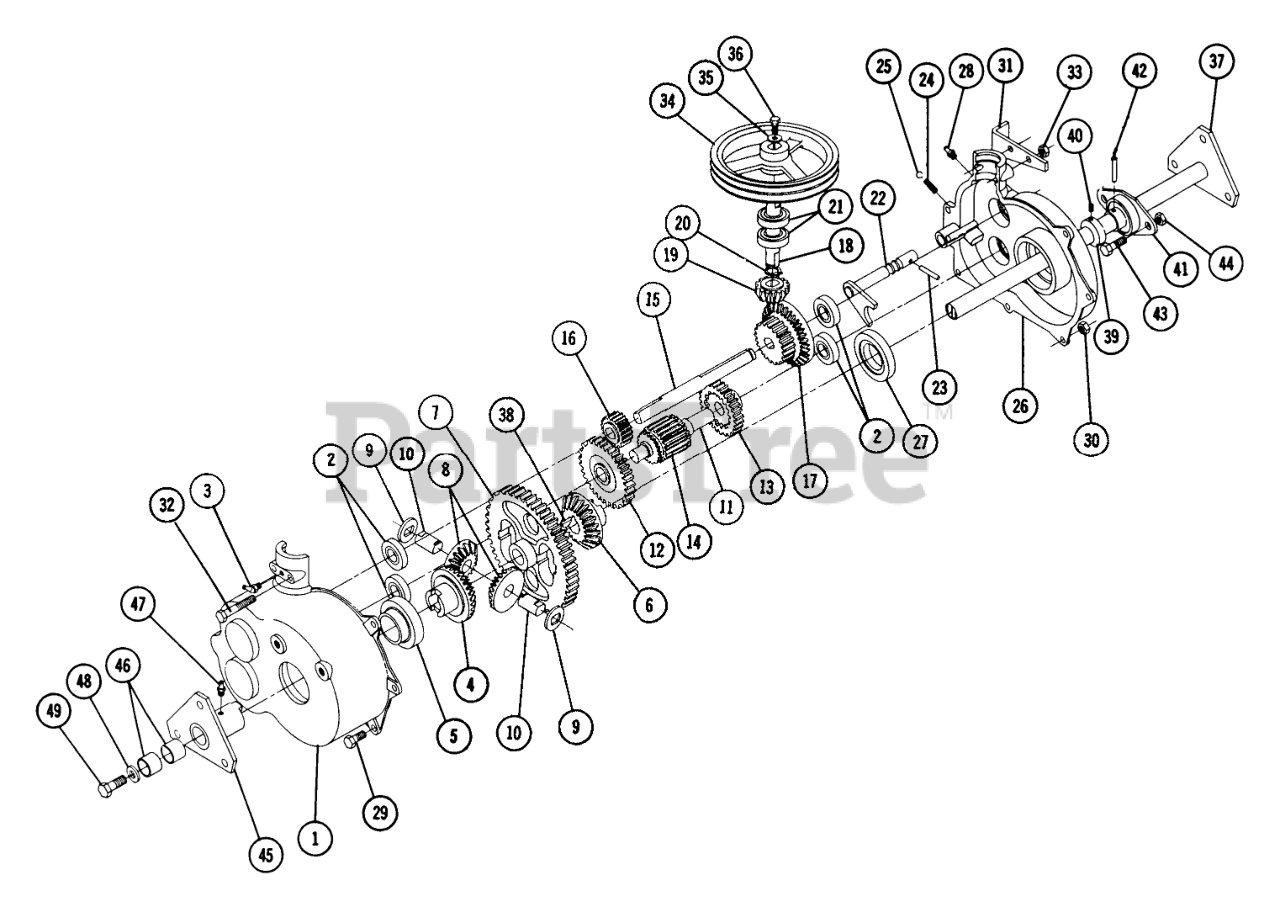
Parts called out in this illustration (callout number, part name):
3	FITTING-GREASE
20	SNAP RING- 5/8 EXT
23	PIN-SPIROL
25	BALL-DETENT
29	Bolt, 5/16-18 X 7/8
30	Nut 5/16-18 Keps
31	Bracket Shift Rod
32	Bolt Hex 5/6-18 X 2-1/2
33	Nut-Nylok
35	Washer
36	Bolt-Hex 5/16-18 x 5/8 Nylok
38	WOODRUFF KEY
40	Set Screw 1/4-20 x 1/4
42	Spirol Pin
43	Bolt Hex 3/8-16 x 5/8
46	BUSHING-BRONZE
47	Fitting
48	WASHER
49	Bolt 3/8-16 x 3/4 Hex
